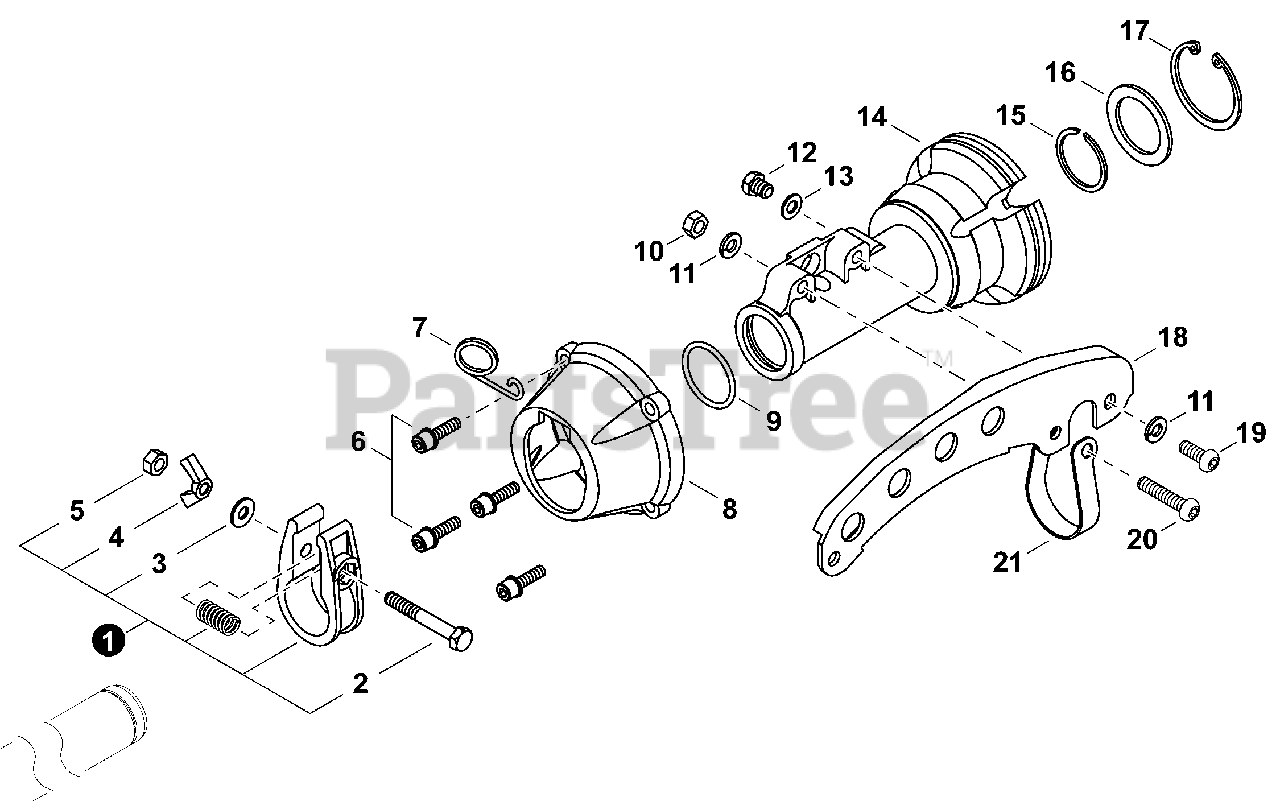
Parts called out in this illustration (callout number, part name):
1	SWIVEL ASSY
2	BOLT
3	WASHER 6 MM
4	NUT, WING M6
5	NUT, LOCK M6
6	BOLT M5x20
7	HOLDER, CABLE
8	CAP, CUSHION
9	O-RING
10	NUT, HEX M6
11	WASHER, SPRING 6
12	BOLT M6x8
13	WASHER
14	CUSHION, AV
15	RING, SNAP
16	STOPPER
17	RING, SNAP 40
18	HANGER
19	BOLT M6x16
20	BOLT M6x30
21	CLAMP
